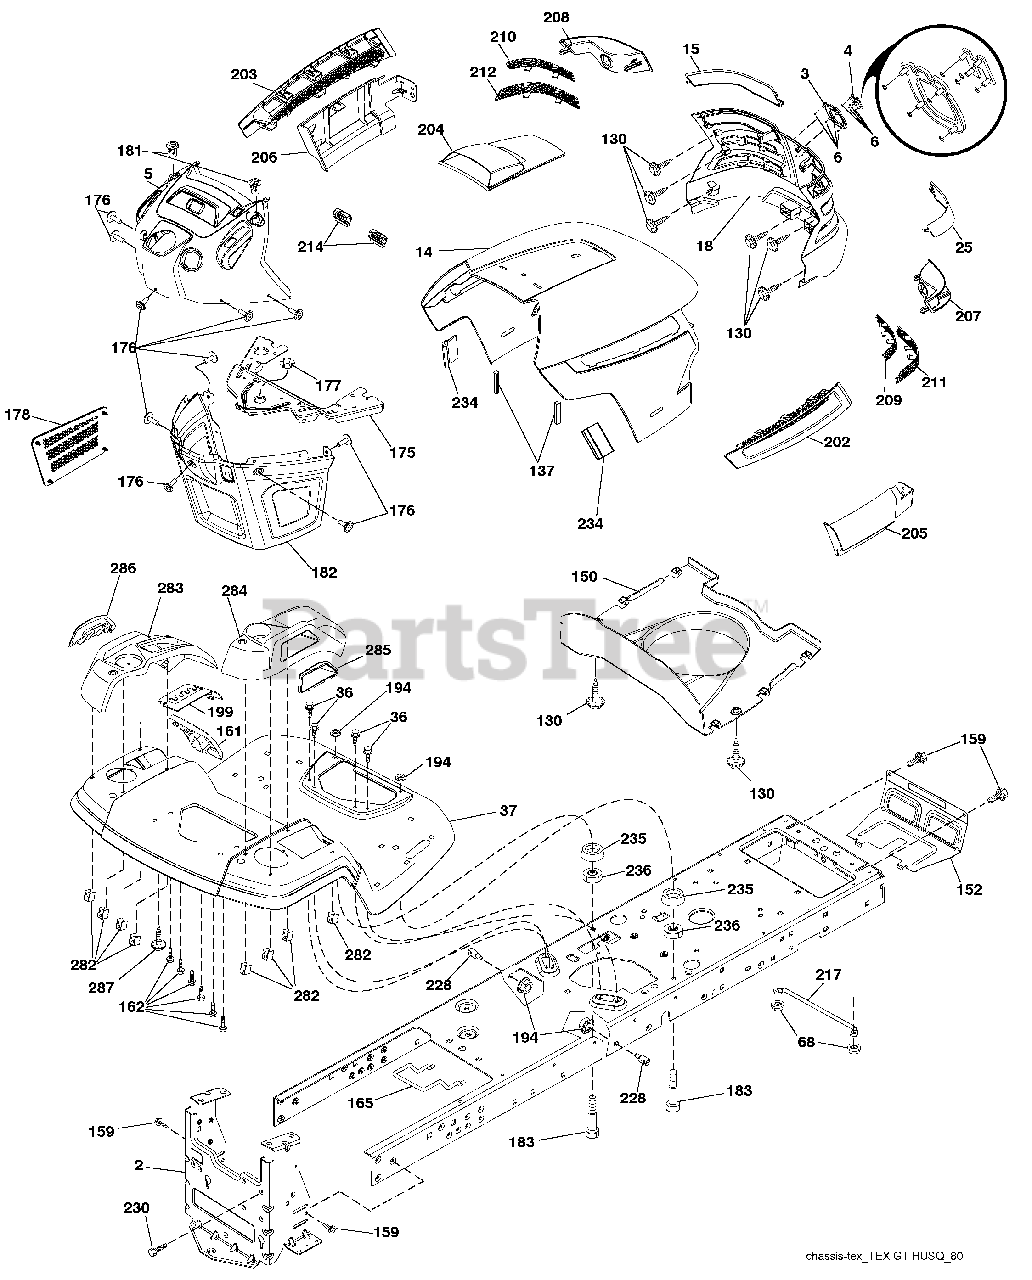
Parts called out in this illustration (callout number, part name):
3	Trim, Husq.
4	Logo
5	Dash
14	Hood
18	Grille/Lens Asm.
36	Screw 5/16-18 x 3/4
68	Screw Thdrol 5/16-18 x 1/2
130	Screw 10 x 0.750 BOS Thread
137	Bumper Dash
152	Shield Browning
159	Screw 3/8-16 x 3/4
161	Window Fuel
162	Screw Hex Wsh Hi-Lo 1/4 x 1/2 unc
165	Support Tank Rear
175	Crossmember
176	Screw 10-24 x 5/8
177	Bushing Steering
178	Cargo Net Asm.
180	Chassis
181	Bushing Mtg. Fender Crgo
182	Dash Lower
183	Bolt 5/16-18 x 1-1/4
194	Nut Lock Hex Flange 5/16-18
199	Plate Deck Lift
202	Vent Side Hood RH
203	Vent Side Hood LH
204	Vent Top Hood
205	Skirt Hood Side RH
206	Skirt Hood Side LH
209	Insert Hex Top RH
210	Insert Hex Top LH
211	Insert Hex Bottom RH
212	Insert Hex Bottom LH
214	Clip Retainer Tinner
228	Stud Fastener
234	Bumper Hood
235	Spacer Fender
236	Nut Lock 5/16-18 unc
282	Clip Retainer Console
283	Console Deck Lift
284	Console Shift
285	Console Insert RH
286	Console Insert LH
287	Screw 1/4-20 X 3/8
